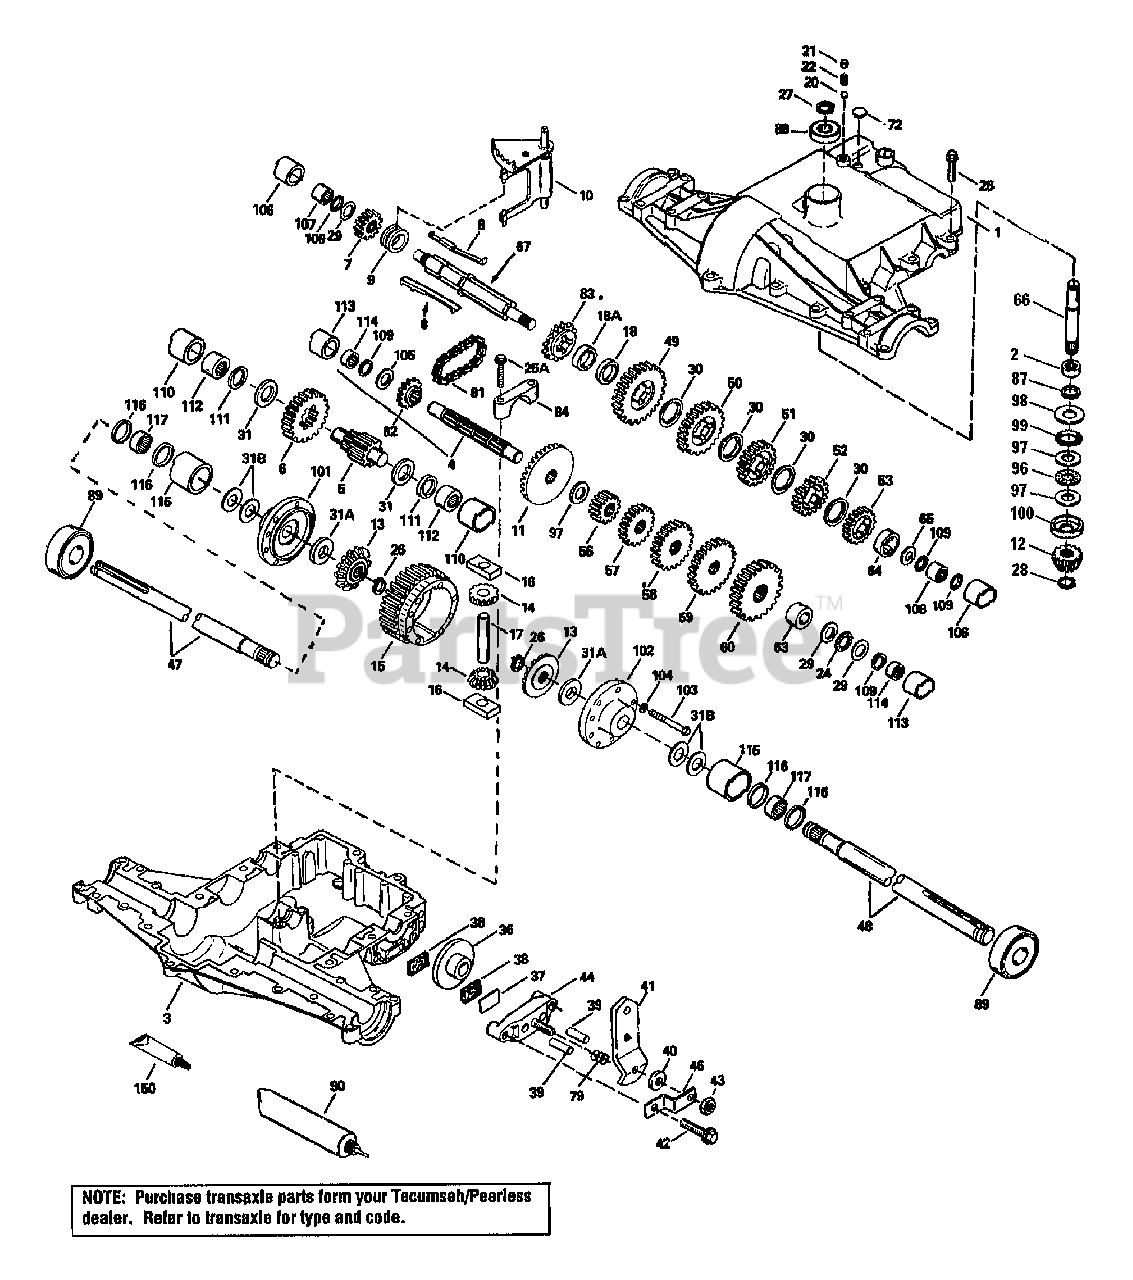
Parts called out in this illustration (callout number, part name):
2	NEEDLE BEARING
4	COUNTERSHAFT
5	OUTPUT SHAFT
6	OUTPUT GEAR
7	SPUR GEAR
8	SHIFT KEY
10	ROD & FORK
11	BEVEL GEAR
12	INPUT PINION
13	BEVEL GEAR
14	BEVEL GEAR
15	RING GEAR
16	DRIVE BLOCK
17	DRIVE PIN
22	SPRING
24	THRUST BEARING
26	RET RING
27	RET RING
28	RET RING
29	WASHER
30	WASHER
36	BRAKE DISK
37	BRAKE PAD PLATE
38	BRAKE PAD
39	DOWEL PIN
41	BRAKE LEVER
49	SPUR GEAR
50	SPUR GEAR
51	SPUR GEAR
52	SPUR GEAR
53	SPUR GEAR
56	SPUR GEAR
57	SPUR GEAR
58	SPUR GEAR
59	SPUR GEAR
60	SPUR GEAR
66	INPUT SHAFT
67	BRAKE SHAFT
81	ROLLER CHAIN
82	SPROCKET
83	SPROCKET
84	BEARING CAP
87	OIL SEAL
89	BALL BEARING
96	THRUST BEARING
107	NEEDLE BEARING
108	NEEDLE BEARING
109	O RING
111	SQUARE-CUT RING
112	NEEDLE BEARING
114	NEEDLE BEARING
116	SQUARE-CUT RING
117	NEEDLE BEARING
150	GASKET ELIMINATOR
